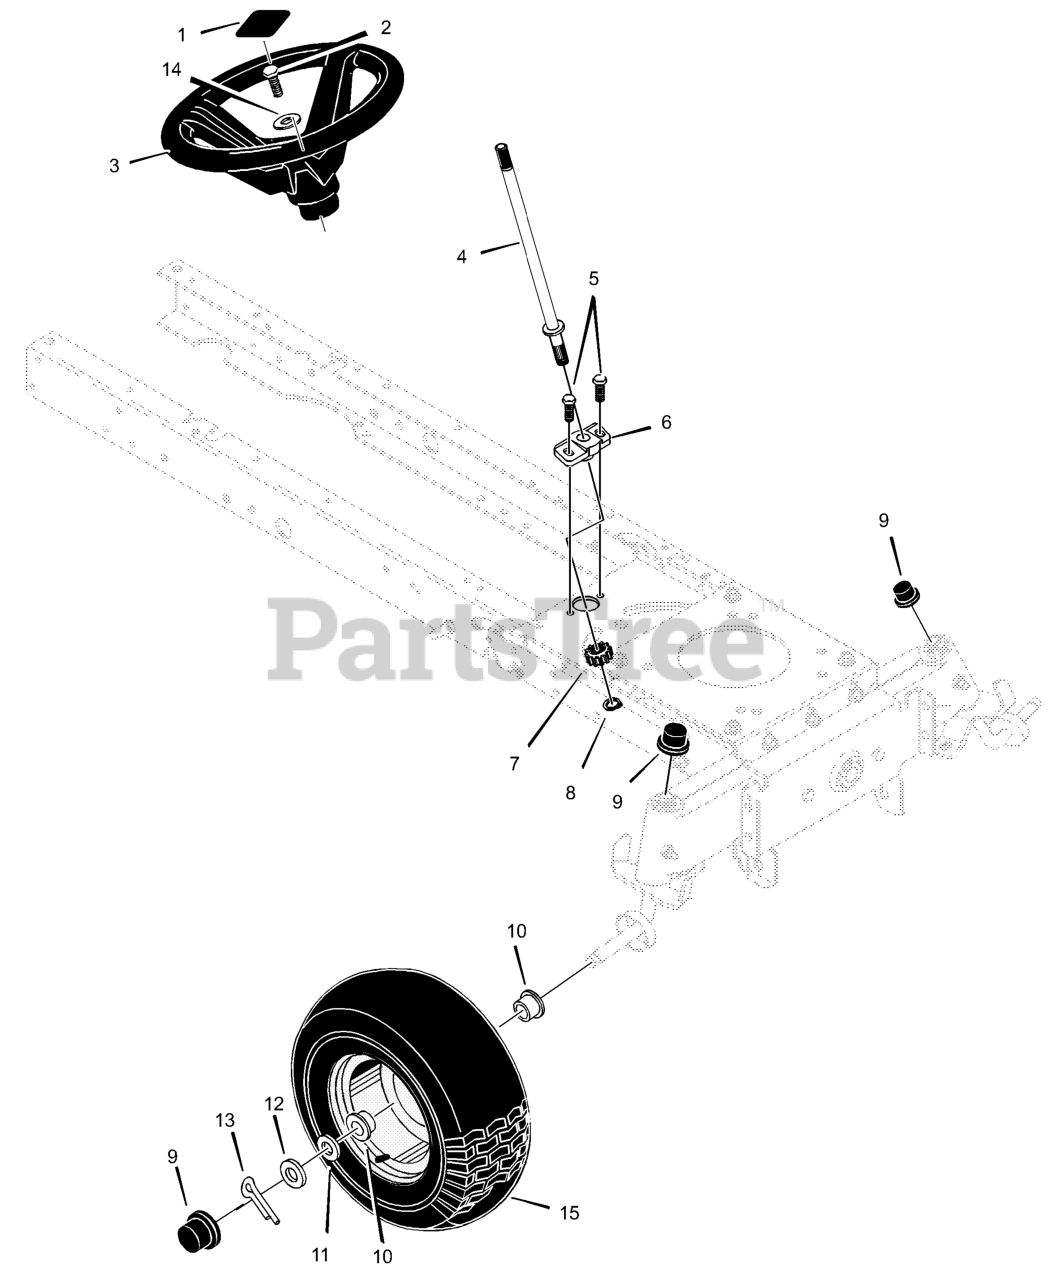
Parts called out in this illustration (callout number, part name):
2	Screw, Hex
3	Wheel, Steering
4	Shaft, Steering
6	Bearing
7	Gear, Pinion
8	Ring, Snap
10	Bearing, Wheel
13	Pin, Cotter
14	Washer
15	Wheel & Tire, Front
